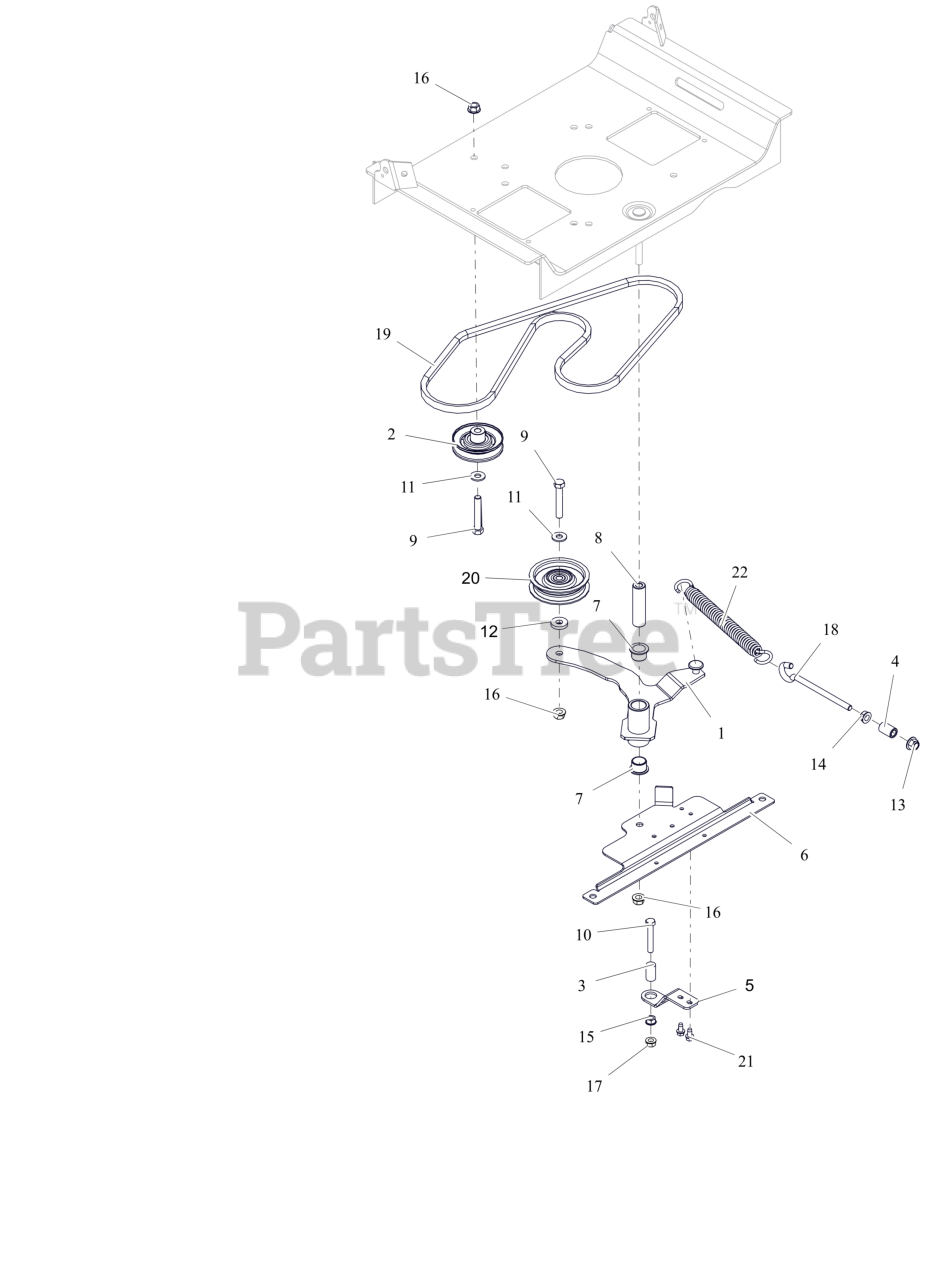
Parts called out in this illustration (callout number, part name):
1	WLDMT,GRD DRIVE IDLER ARM-LGR
2	IDLER, V-3.000 OD
3	SPACER, RUBBER 5/16 IDX1.0 LG
4	SPACER, .375X.625X.970 (PM)
5	BRKT, CLUTCH STOP (XL)
6	BRKT-IDLER ATTACHMENT
7	BSHG-FLG 0.75X0.875X.625X1.125
8	BUSHING, SLEEVE .38X.750X2.78
9	BLT,HEX .38-16X2.25 G5 ZCC
10	BLT, HEX .31-18X2.00 G5 ZCC
11	WSHR,FLT .375X.875X.083 ZCC
12	WSHR, FLT .406X1.00X.188 ZCC
13	NUT,NYL-FLG .38-16 GF ZCC
14	NUT, SPNLK-FLG .38-16 G5 ZCC
15	NUT,SPNLK-FLG .31-18 G5 ZCC
16	NUT-LK-TOP-FLG .38-16 ZC120
17	NUT-LK-TOP-FLG .312-18 GF ZCC
18	BOLT,.38-16 X 4.25-.62 DIA EYE
19	V-BELT, A-RAW EDGE
20	SHEAVE, IDLER -V .38 x 4.00
21	SCR-TAP .25-20X.50 HWH ZCC
22	SPRING, EXTENSION
